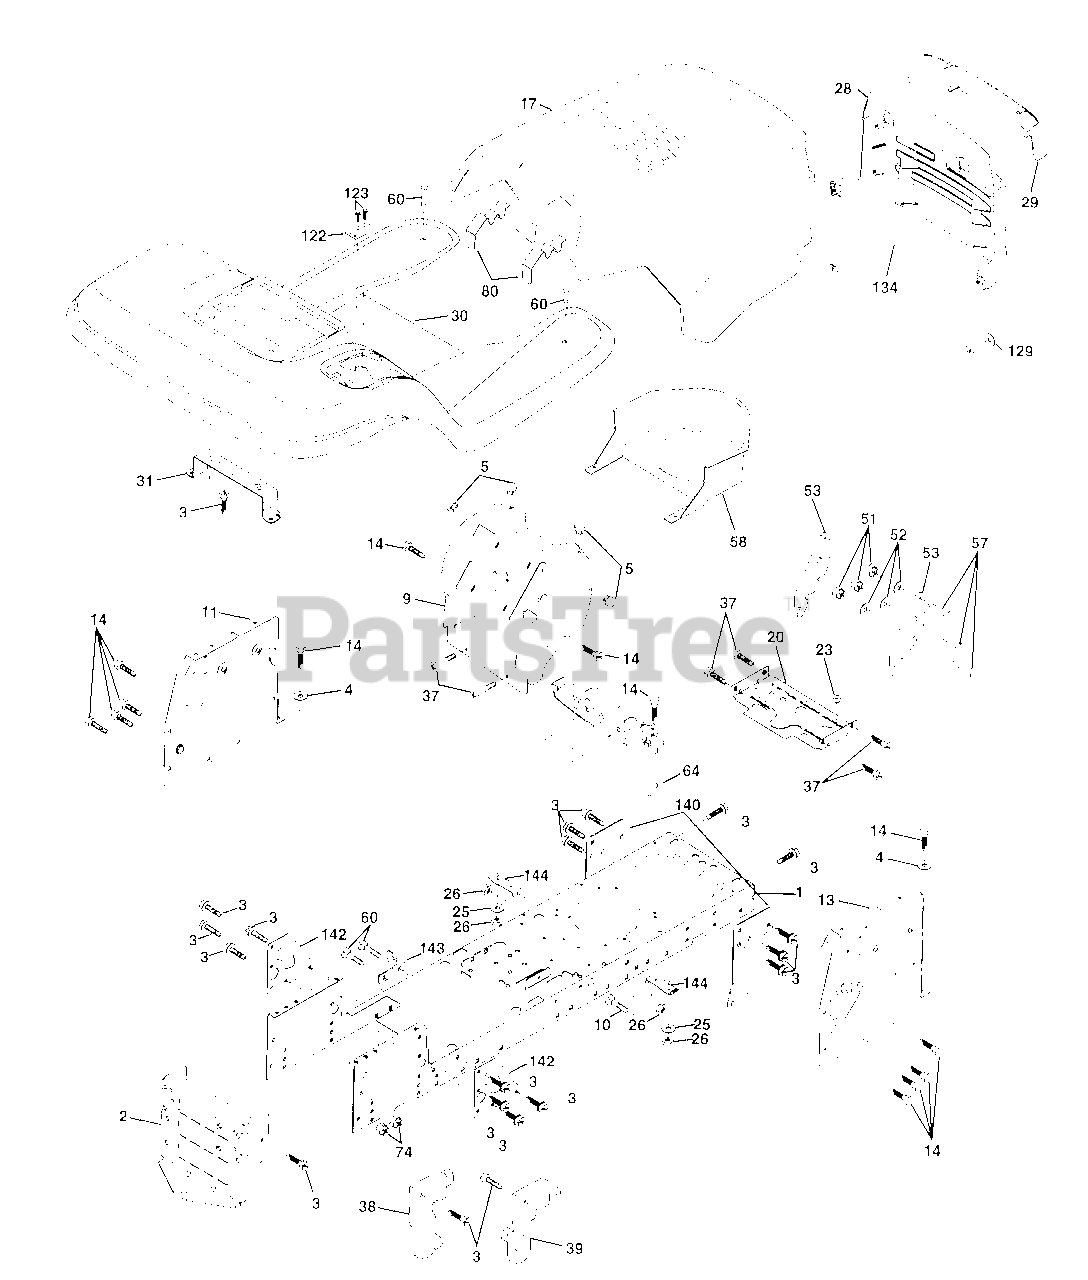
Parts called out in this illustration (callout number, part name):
1	Chassis Weldment
2	Drawbar, Stretch
3	Screw Thdrol 3/8-16 x 3/4 Ty-tt
4	Washer 13/32 x 3/4 x 16 Ga.
5	Bumper Hood/Dash
9	Dash P/L M, N/AMM N/HM Grey
10	Bolt Carriage 3/8-16 x 1
11	Panel Dash Lh
13	Panel Dash Rh
14	Screw Thdrol 3/8-16 x 1/2 Ty-tt
17	Hood LT/PL Husqvarna
20	Plate Mtg Battery Fuel Tank Fr
25	Washer 13/32 X 13/16 X 12 Ga
26	Nut Lock Hex W/Ins 3/8-16 Unc
28	Grille LT/PL Husqvarna
29	Lens ET/PL Husqvarna
30	Fender Footrest STLT Pnt
31	Bracket Support Fender
37	Screw Thdrol 6/16-18 x 1/2 TYT
38	Bracket, Asm. Pivot, L.H., Mower Rear
39	Bracket, Asm. Pivot, R.H., Mower Rear
51	Nut Lock Hex W/Ins 1/4-20
52	Washer 9/32 x 7/8 x 16 Ga.
53	Bracket Pnt. Pick off LT/PL Husqvarna
57	Bolt Hex 1/4-20 x 3/4
58	Air Duct Engine P/L
60	Bolt Rdhd Sqnk 3/8-16 unc x 3/4
64	Dash Lower STLT
74	Nut Crownlock 3/8-16 UNC
80	Latch Hood Plm Husqvarna
129	Washer 9/32 x 5/8 x 16 Ga.
134	Rod Support Hood LT/PL Husq.
140	Bracket Chassis Front 7 Ga.
142	Plate Reinforcement STLT
143	Bracket Swaybar Chassis
144	Bracket Pnt Footrest STLT
146	Screw Torx Hd Thd 5/16-18 UN-2A
